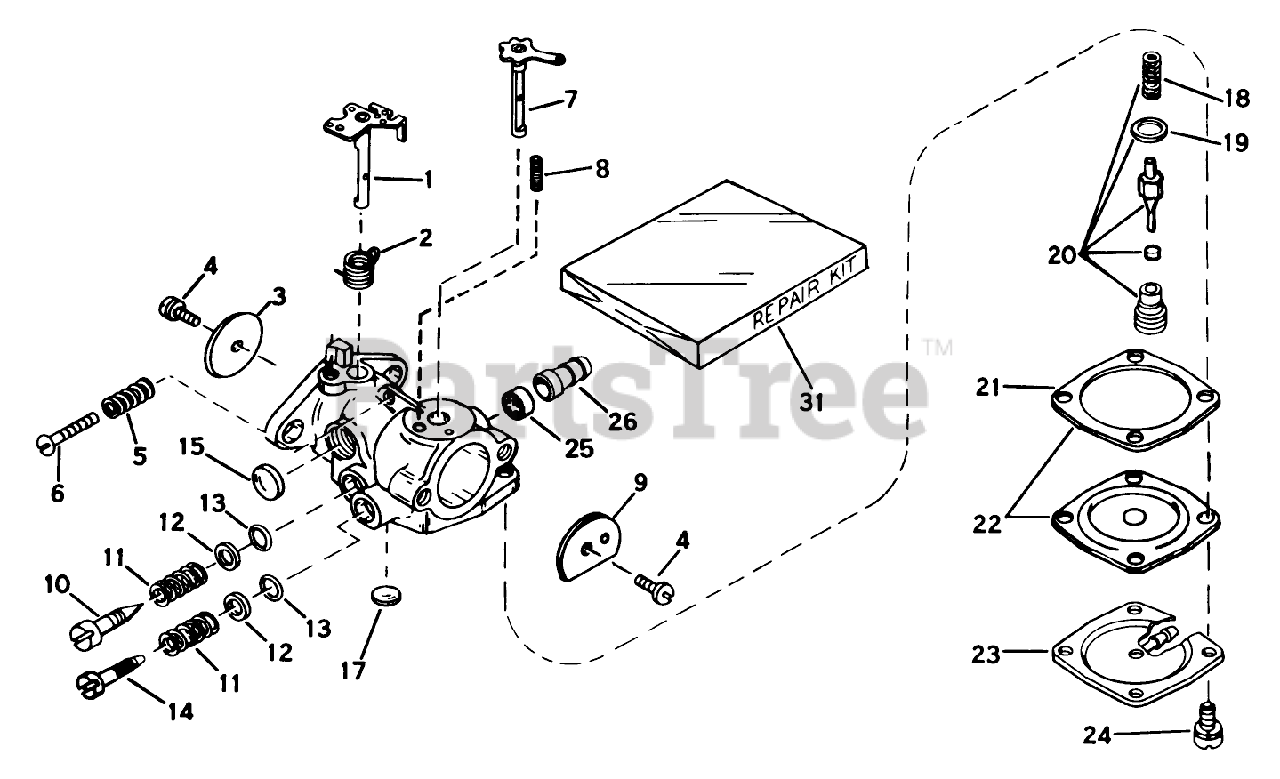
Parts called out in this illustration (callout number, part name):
1	Shaft Lever Assy., Throttle
2	Spring Return
3	Shutter, Throttle
4	Screw-Shutter
5	Spring-Tension
6	Screw-Throttle Crack Screw / Idle Speed
7	Shaft Lever Assembly
8	Spring-Positioning, Choke
10	Screw-Idle Adjustment
11	Spring
12	Washer
13	ORing
14	Screw Main Adjustment
15	Plug-Welch, Idle Mixture Well
17	Plug Welch
18	Spring-Valve
19	Gasket-Valve Seat
20	Inlet Needle, Seat, Spring Gasket Assy. (lncl. #1819)
21	Gasket-Diaphragm
22	Diaphragm Ass. (Incl. No. 21)
23	Cover, Diaphragm
24	Screw, Diaphragm Cover
25	Valve Check
26	Fuel Fitting
31	Repair Kit
